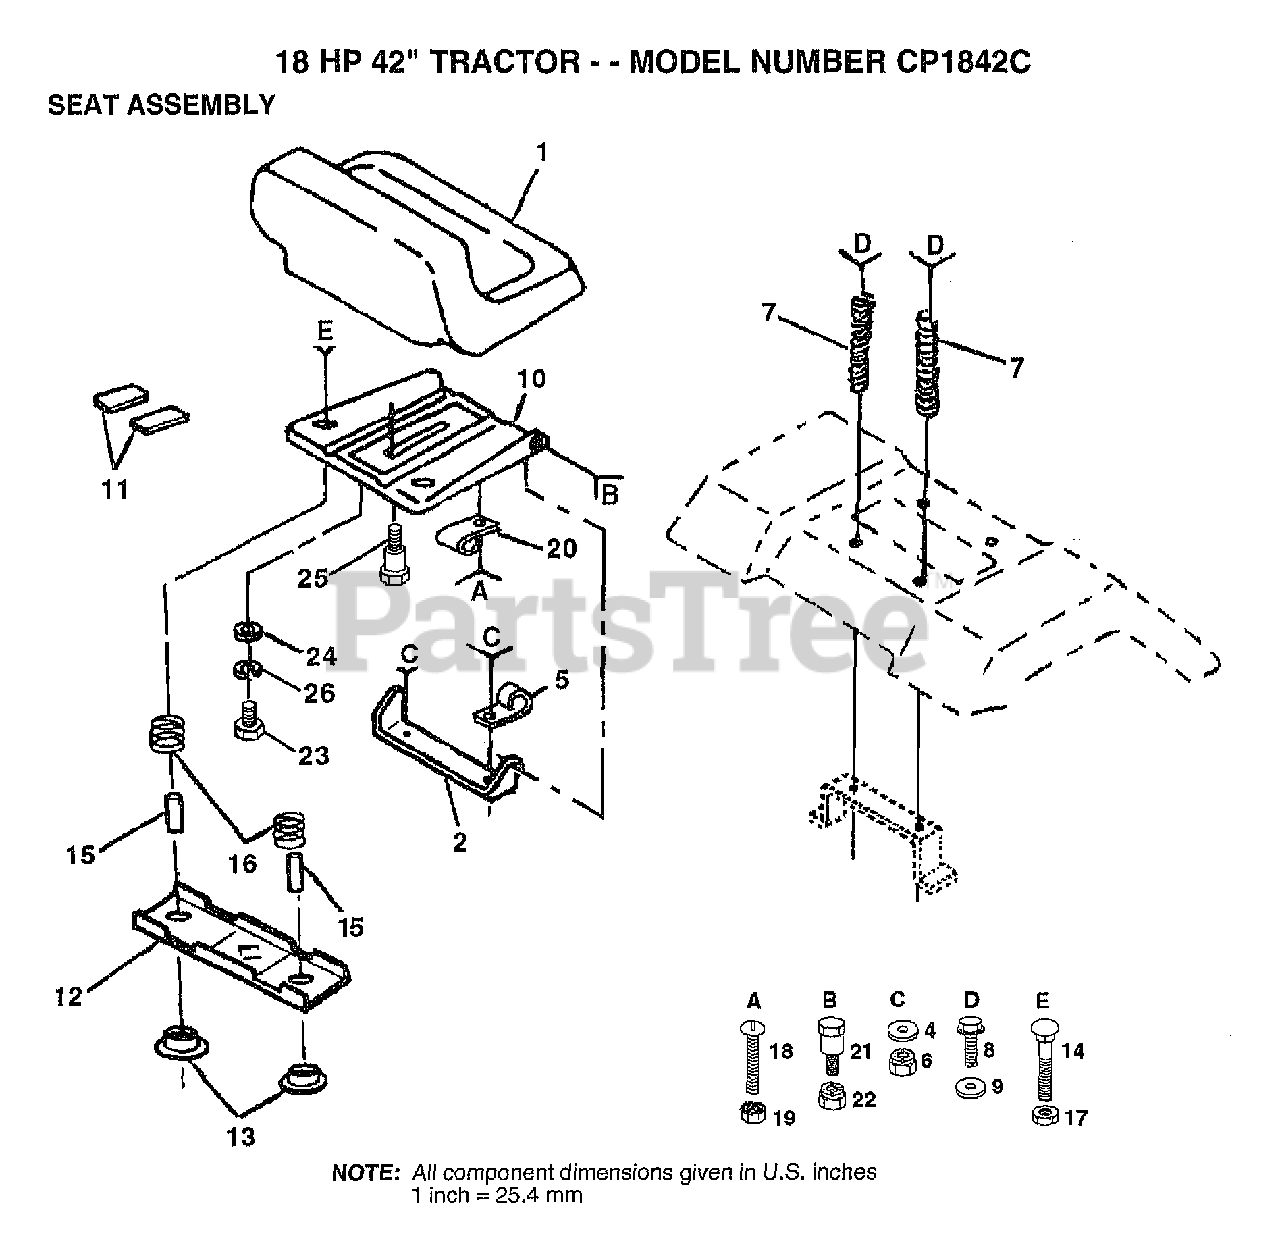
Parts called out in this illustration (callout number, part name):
4	WASHER
5	CLIP T
7	SPRING COMPRESSIO
8	SCREW LT
9	WASHER
11	STRIP FORM
12	BRKT SWITCH
13	BUSHING
15	SPACER SPLIT
16	SPRING COMPRESSED
19	"NUT,KEPS"
23	BOLT
24	WASHER
25	"BOLT,SHOULDER"
26	LOCKWASHER
